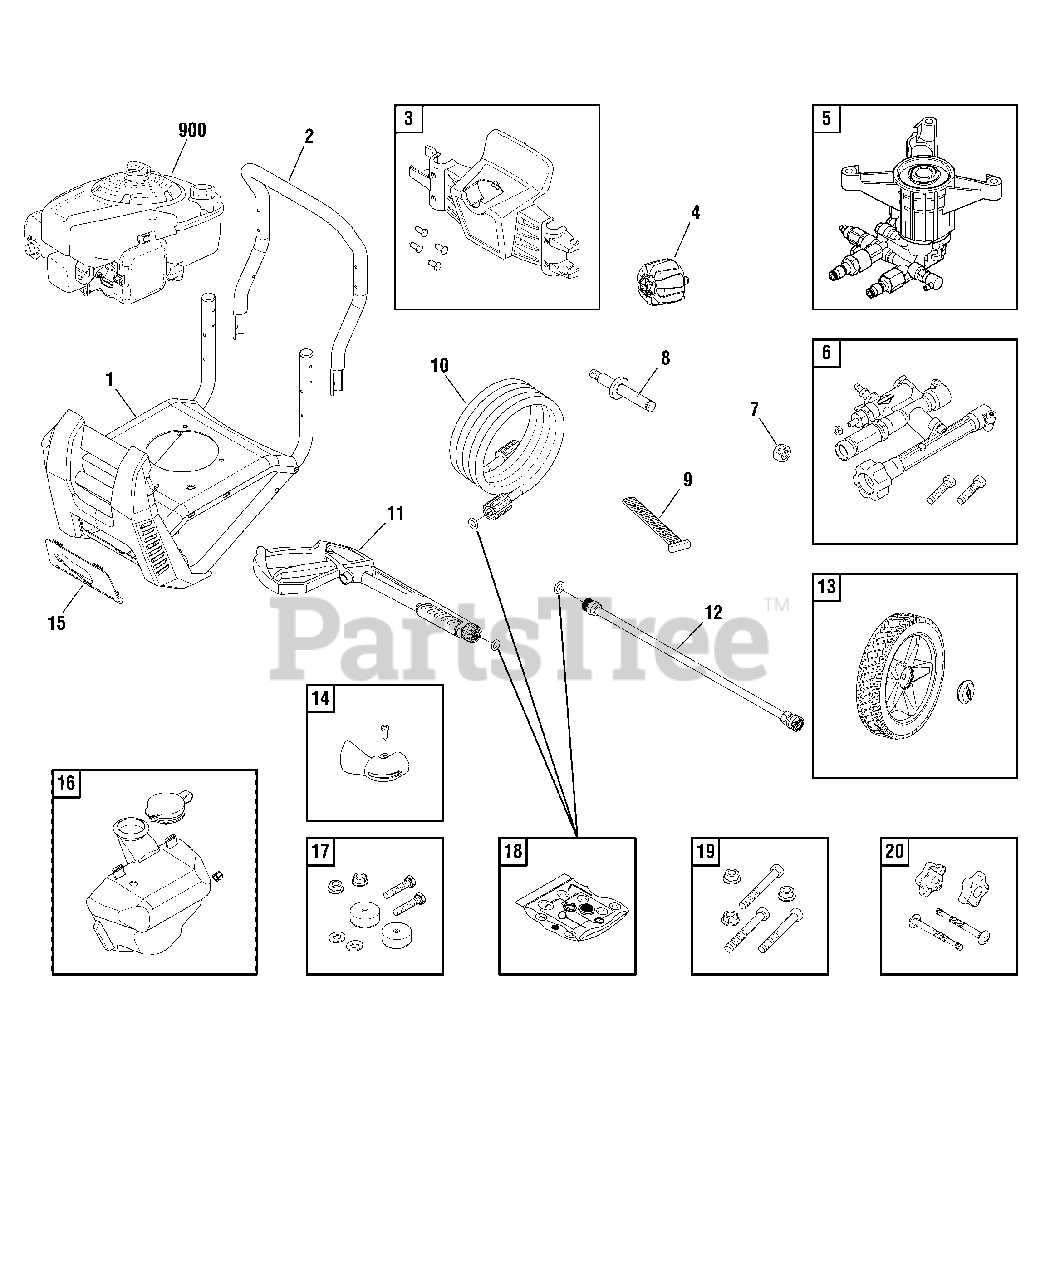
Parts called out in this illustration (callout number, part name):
6	POWERFLOW
10	HOSE
11	GUN
12	EXTENSION-QC
14	DEFLECTOR-EXHAUST
16	TANK-CHEMICAL
17	MOUNT-VIBRATION
19	KIT-HARDWARE PUMP MOUNTING
20	KIT-HARDWARE HANDLE
900	** ENGINE
